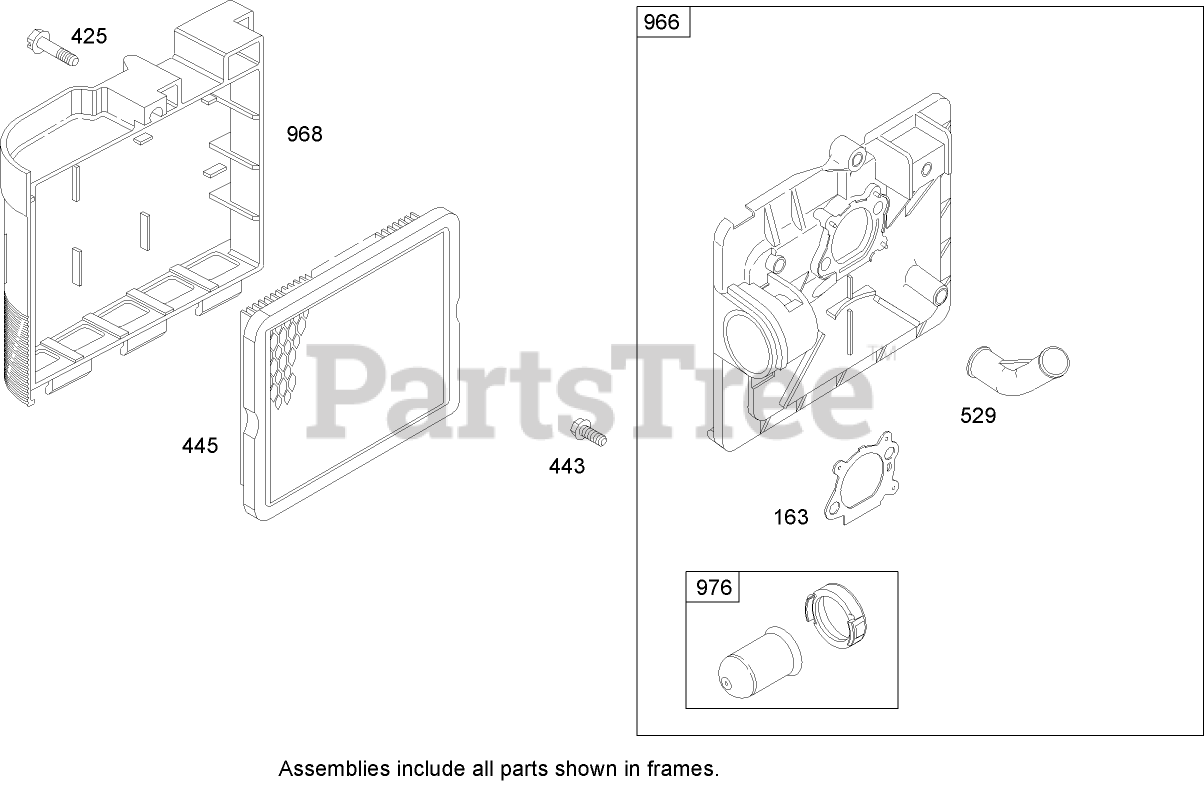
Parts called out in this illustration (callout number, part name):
163	Gasket-Cleaner, Air
425	Screw
443	Screw
445	Filter-Cartridge, Air Cleaner
529	Grommet
966	Base-Primer, Air Cleaner
968	Cover-Cleaner, Air
976	Primer-Carburetor
